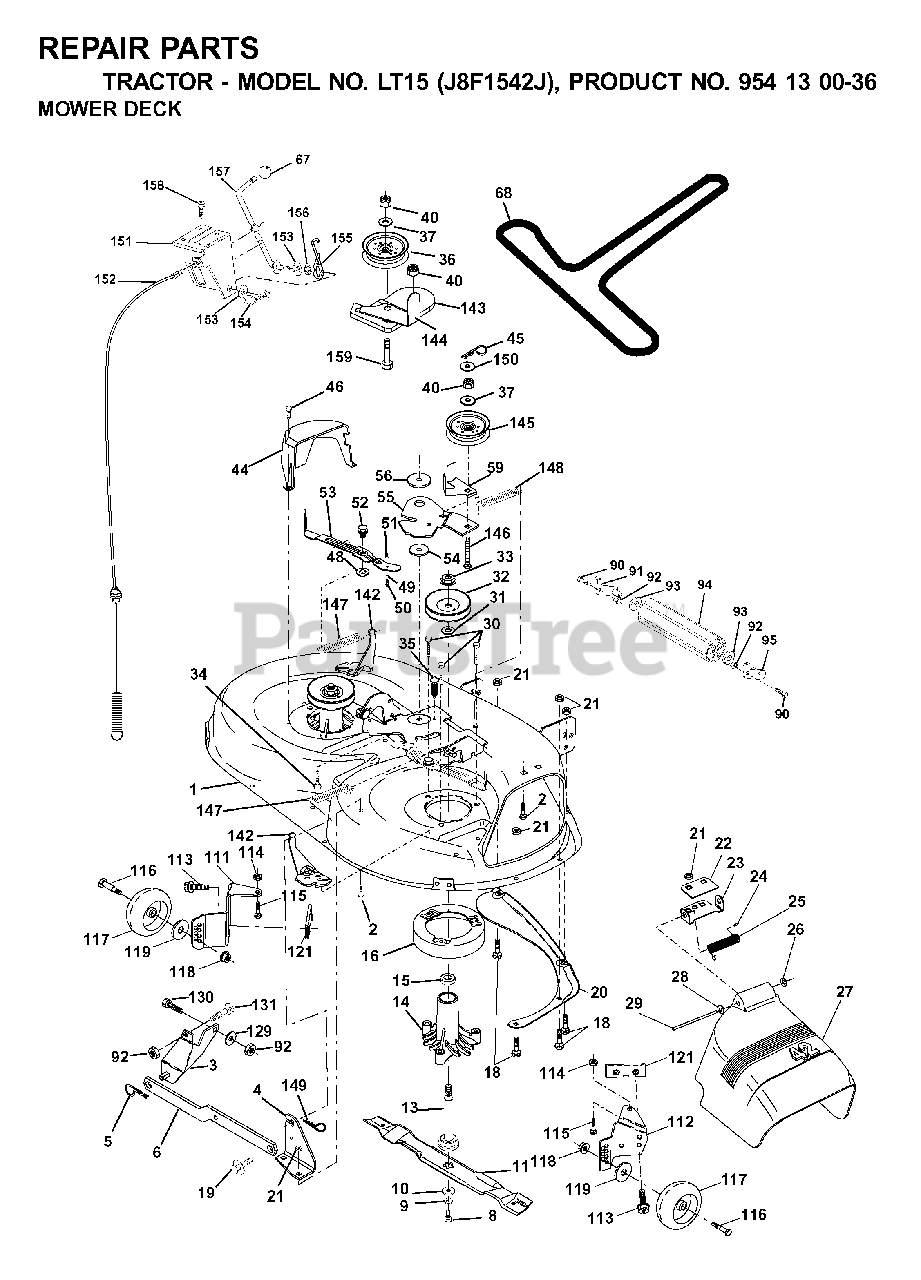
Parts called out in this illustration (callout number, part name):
1	42" DECK KIT
2	BOLT
3	BRKT ASM SWAY BAR
4	BRACKET SWAY BAR 42" DECK
5	RETAINER-SPRNG RB
6	REAR SUSP ARM
8	BLADE BOLT
9	LOCKWASHER
10	WASHER.BLADE
11	BLADE 42"
13	SHAFT ASM VENT
14	HSG MANDREL
16	STRIPPER
18	BOLT
19	BOLT SHD 5/16-18
20	BAFFLE.VORTEX
21	LOCKNUT
22	STIFFENER BRACKET
23	DEFLECTOR BRACKET
24	CAP-SLEEVE LT
25	SPRING TORSION
26	NUT PUSH M
27	SHIELD DEFLECTOR
28	WASHER
29	ROD.HINGE
30	SCREW THDROL ROLLING WASHER HD
31	WASHER
32	PULLEY/MANDREL
33	NUT
34	BOLT
35	FASTENER.XMAS.TREE
36	FLAT IDLER PULLEY
40	LOCKNUT
44	GUARD MANDREL LH BLACK
45	RETAINER M
46	SCREW.1/4-20X5/8
49	ROLLER ASM CAM FOLLOWER
50	BOLT
53	ARM
54	HARDENED WASHER
55	ARM IDLER 42" MOWER LT/YT
56	SPACER.RETAINER.MOWER
59	GUARD, BELT
67	KNOB T (3/8 HOLE)
68	BELT V SECONDARY
90	BOLT
91	BRACKET LH (A)
92	NUT
94	NOSE ROLLER
95	BRACKET RH (B)
111	BRACKET WHEEL GAUGE LH 42" DK
112	BRACKET WHEEL GAUGE RH 42" DK
114	NUT
115	BOLT
117	WHEEL.GAUGE.STANDARD
118	LOCKNUT
119	WASHER
121	BRACKET.EXTRD.GWL
129	WASHER
131	BOLT D
142	ARM SPRING BRAKE MOWER
143	BRACKET, ARM IDLER
144	KEEPER.BELT.42".CLUTCH.CABLE
145	PULLEY
146	BOLT, CARRIAGE IDLER BLACK
147	SPRING EXTENSION
148	IDLER RETURN SPRING
149	SPRING.RETAINER.YELLOW.ZINC
150	WASHER PM
151	BRACKET, CLUTCH CABLE
152	CLUTCH CABLE 42"
153	WASHER FLAT 3/8"
154	SPRING RETAINER
155	SPRING RETENTION LEVER
156	SPACER CLUTCH CABLE
157	ROD CLUTCH CABLE 3/8"
158	SCREW LT
159	BOLT
